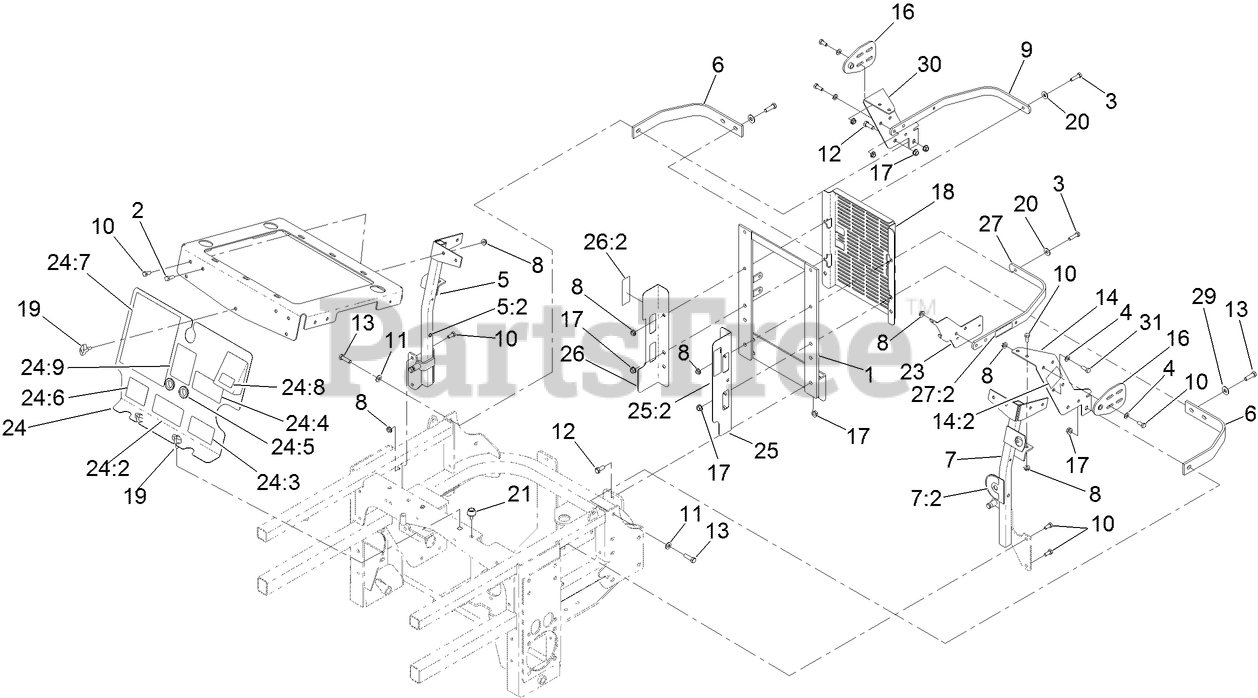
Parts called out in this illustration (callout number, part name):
1	SUPPORT-RADIATOR, REAR
2	SCREW-HH
3	SCREW-HH
4	WASHER-PLAIN
5	RH RADIATOR BRACE ASM
5:2	NUT-CLINCH
6	STRAP-GUARD
7	LH RADIATOR BRACE ASM
7:2	DECAL-VALVE, FUEL
8	NUT-HF
10	SCREW-HH
11	WASHER-FLAT
12	SCREW-HH
13	SCREW-HH
14	LH SUPPORT BRACKET ASM
14:2	DECAL-FUSE
16	PLATE-PIVOT, HOOD
17	NUT-HHF, WHIZ
18	SHIELD-COOLER
20	WASHER-FLAT
21	BUMPER-RUBBER
23	BRACKET-RELAY, FUSE
24	FRONT ENGINE SHIELD ASM
24:2	DECAL-DANGER, ROTATING DEVICES
24:3	DECAL-ROUTING, HYDRO BELT
24:4	DECAL- WARNING, BUZZER
24:5	GROMMET-RUBBER
24:6	DECAL-ROUTING, CLUTCH BELT
24:7	DECAL-CHECK, SERVICE
24:8	DECAL-CAUTION
24:9	DECAL-COOLANT
25	GUARD-FAN, LH (CE)
25:2	DECAL-DANGER
26	GUARD-FAN, RH (CE)
26:2	DECAL-DANGER
27	TOP STRAP ASM
27:2	DECAL-RELAY
29	WASHER-FLAT
30	BRACKET-SUPPORT, RH
31	SCREW-HH
